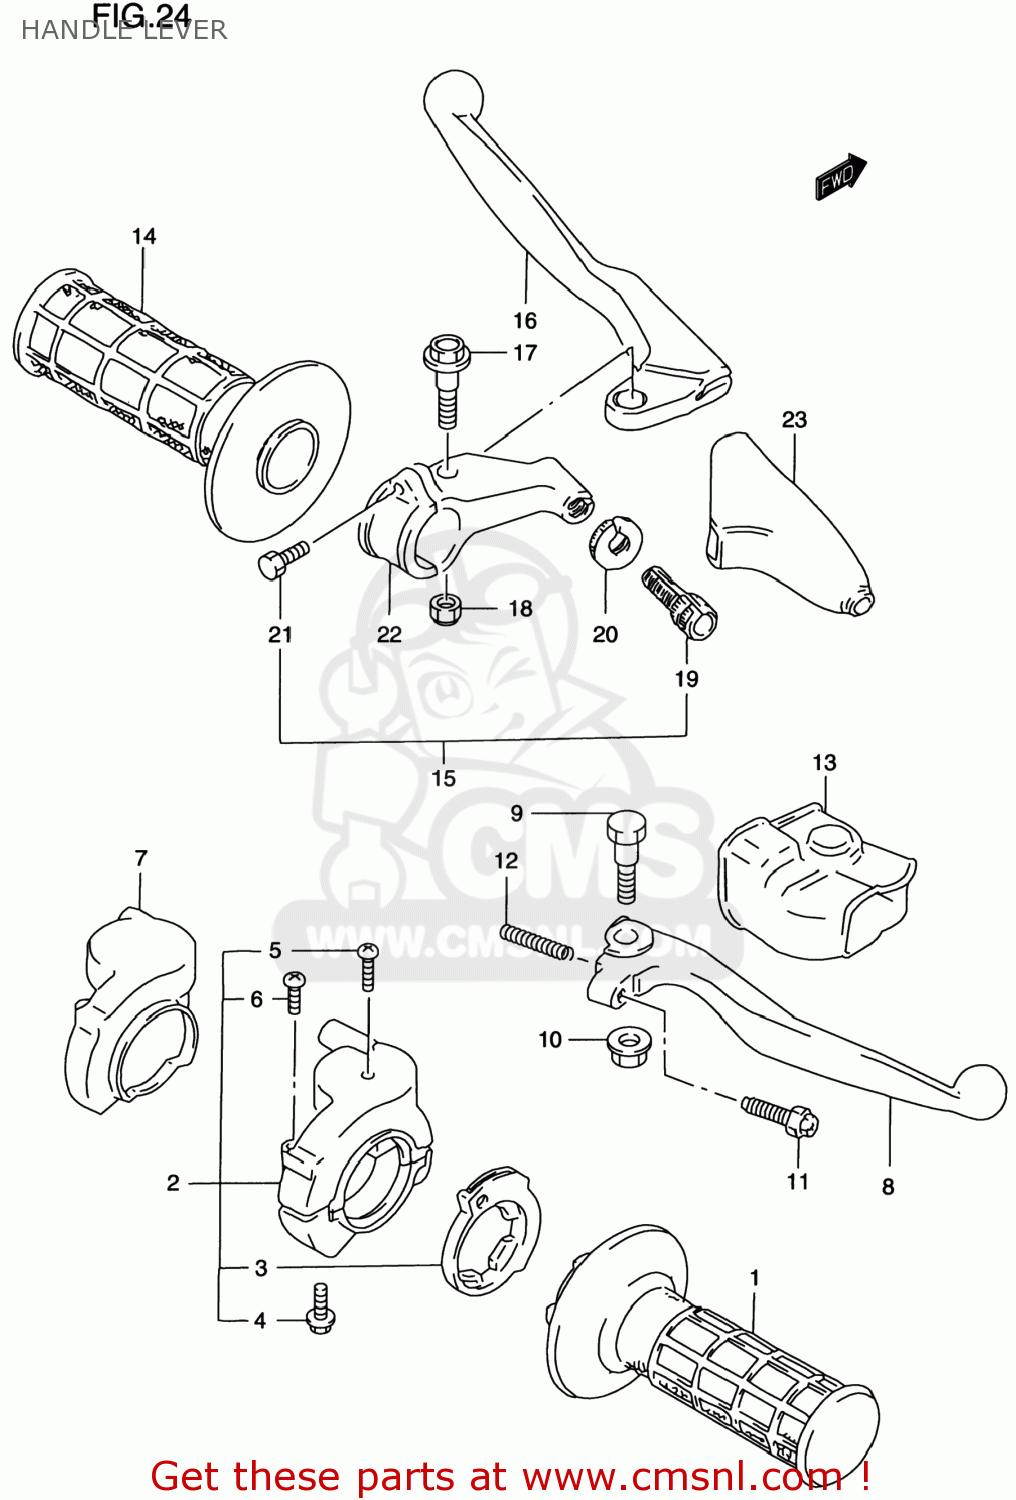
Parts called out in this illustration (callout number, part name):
1	GRIP,THROTTLE
2	CASE ASSY,THROTTLE
3	ROTOR,THROTTLE
4	SCREW
5	SCREW,UPPER
6	SCREW
7	COVER,THROTTLE CASE
8	LEVER,BRAKE
9	BOLT,BRAKE LEVER
10	NUT
11	BOLT,ADJUSTER
12	SPRING,RETURN
13	COVER,BRAKE LEVER
14	GRIP,L
15	LEVER ASSEMBLY,CLUTCH
16	LEVER,CLUTCH
17	BOLT,LEVER
18	NUT 6MM
19	ADJUSTER,WIRE
20	NUT,LOCK
21	BOLT
22	BRACKET,LEVER HOLDER
23	COVER,CLUTCH LEVER
